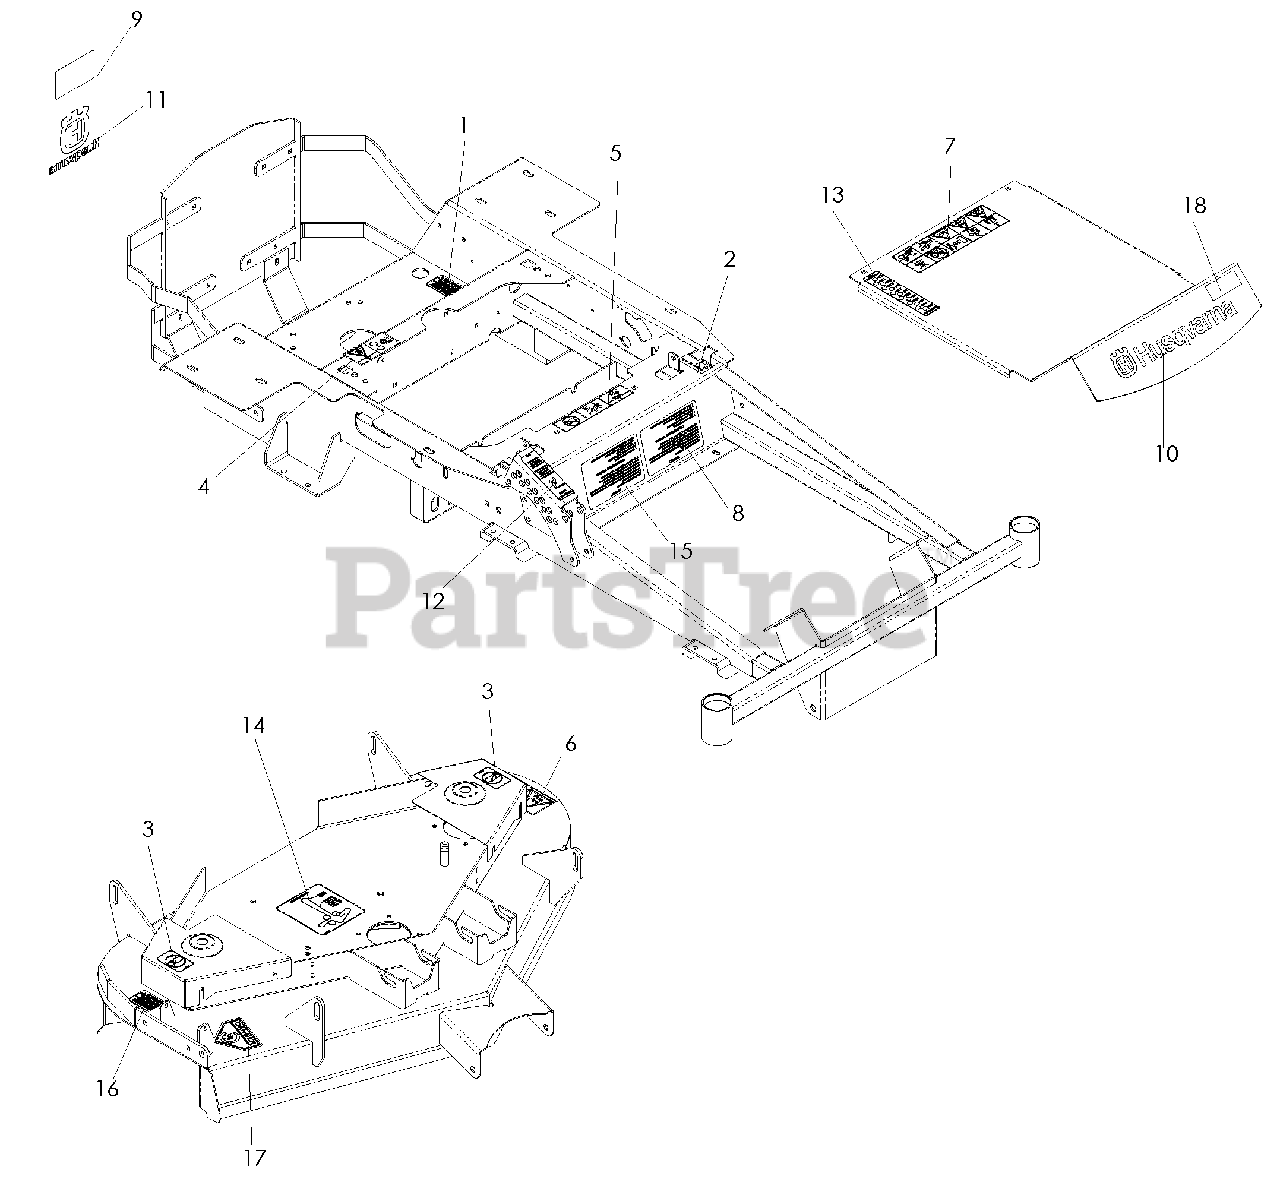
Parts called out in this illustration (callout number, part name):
1	DECAL, PROP 65
2	DECAL, MOTION CONTROL
3	DECAL, NO STEP
4	DECAL, DANGER BELT
5	DECAL, BATTERY WARNING
6	DECAL, SEVERING
7	DECAL, WARNING
8	DECAL, START
9	DECAL, DO NOT TOW
10	DECAL, HUSQVARNA
11	DECAL, CROWN
12	DECAL, TRNSPRT RELEASE
13	DECAL, HEIGHT ADJUST
14	DECAL, BELT ROUTING
15	DECAL, WARNING
16	DECAL, CAUTION
17	DECAL, WARNING
18	DECAL, EZ4220
